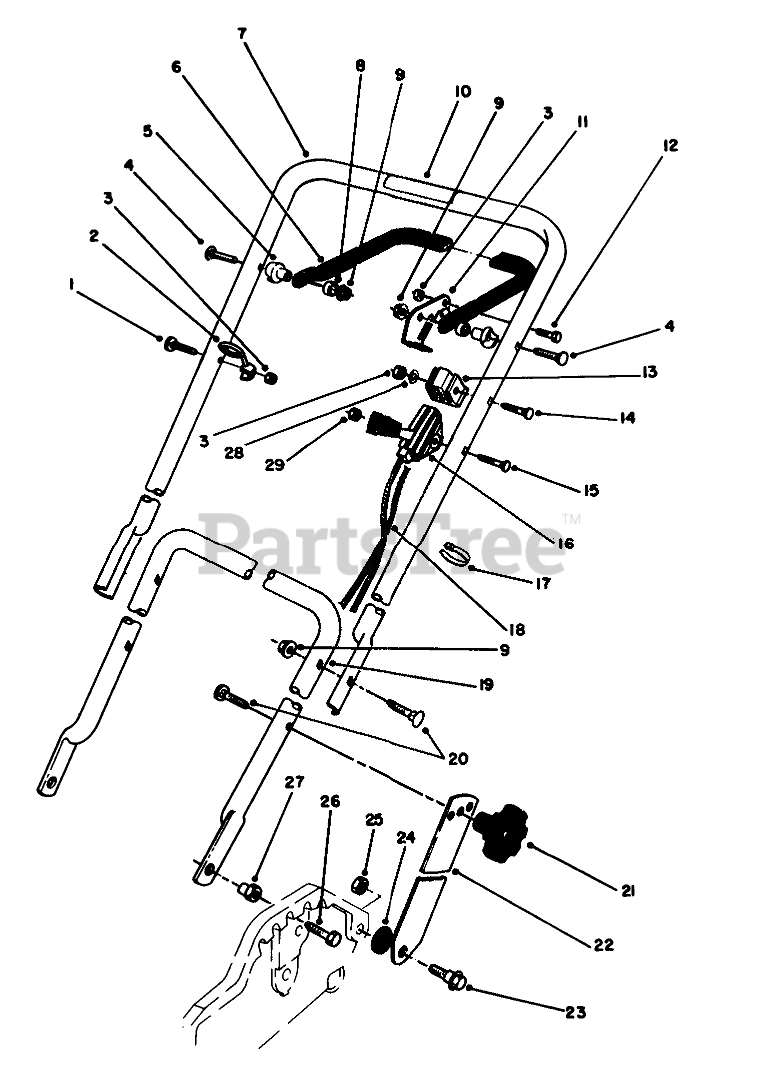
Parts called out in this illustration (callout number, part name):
1	HANDLE SCREW
2	Guide
3	NUT-LOCK, NI
4	5/16-18 X 2 HNDLE SCREW
5	SPACER-SUPPORT
6	Bar-Control
7	Handle-Upper (Incl. Ref. #10)
8	SPACER-NYLON
9	NUT-LOCK, NI
10	DECAL - HANDLE
11	LEVER-CONTROL
12	SCREW-HH
13	SUPPORT-CABLE
14	HANDLE SCREW
15	SCREW-HANDLE
16	THROTTLE CONTROL
17	TIE-CABLE
18	BRAKE CABLE
19	LOWER HANDLE
20	SCREW
22	Handle Latch
23	SCREW-SHOULDER
24	SPACER
25	NUT-LOCK, NI
26	SCREW-HH
27	HANDLE PIVOT NUT
28	WASHER-FLAT
29	NUT-LOCK, NI
